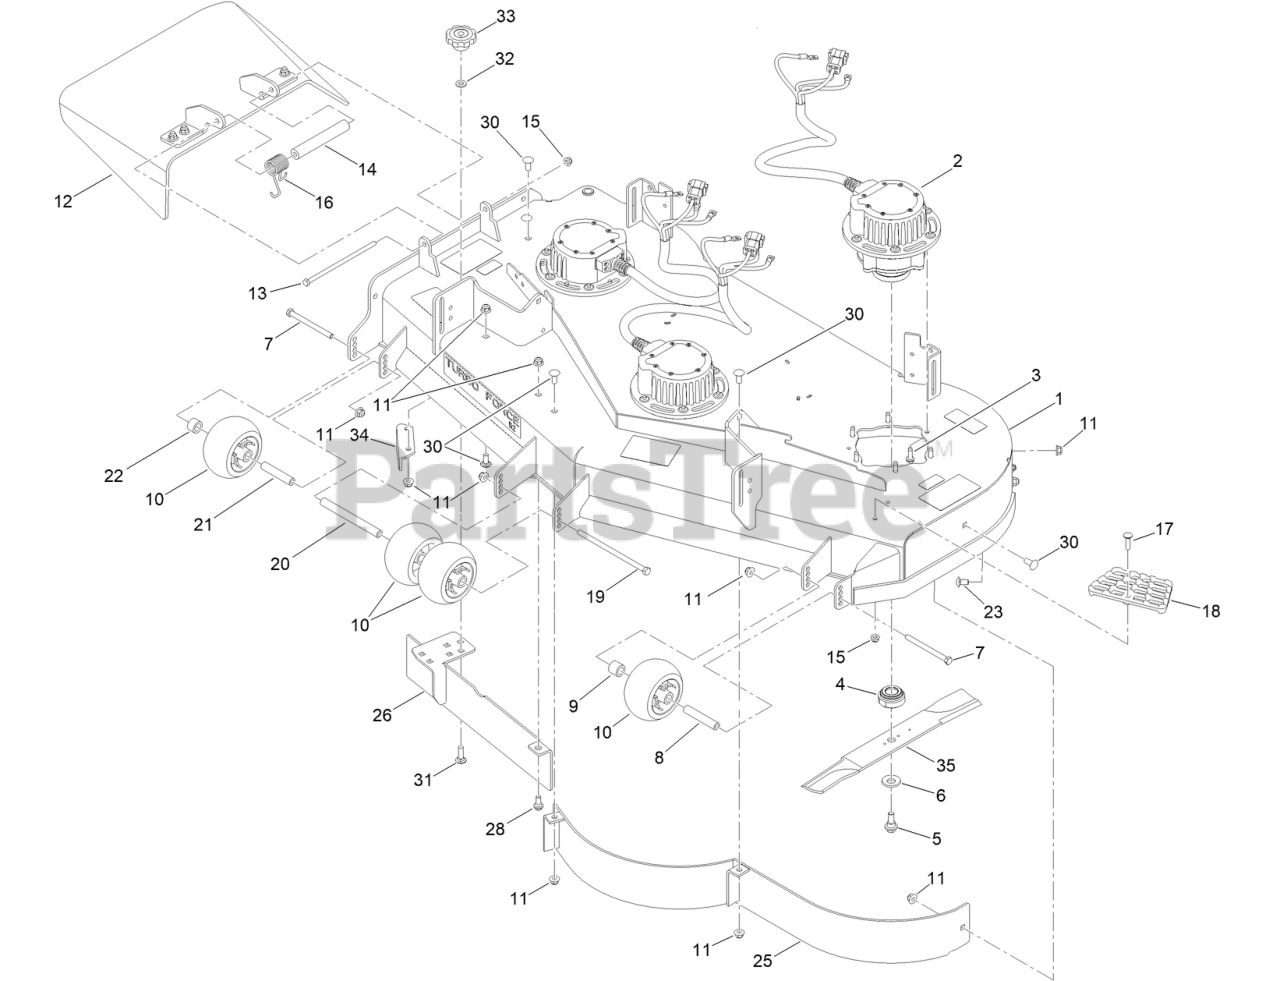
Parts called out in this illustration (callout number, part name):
1	DECK ASM-52IN
2	MOTOR/GEN-48V,
3	SCREW-THD ROLL, HWH
4	RETAINER-BLADE
5	SCREW-SHOULDER,HWH
6	WASHER-BELLEVILLE
7	SCREW-HH
8	TUBE-SPANNER
9	TUBE-SPACER
10	ROLLER-SCALP, ANTI
11	NUT-HF, NI
12	RUBBER DEFLECTOR ASM
13	SCREW-HH
14	SPACER
15	NUT-HF, NI
16	SPRING-TORSION
17	SCREW-CARR
18	STEP-DECK
19	SCREW-HH
20	SPACER-WHEEL
21	TUBE-SHAFTING
22	TUBE-SPACER
23	SCREW-CARR
25	BAFFLE ASM
28	BOLT-SHOULDER
30	SCREW-CARR
31	BOLT-CARR
32	WASHER-HARDENED
34	BAFFLE-DISCHARGE
35	BLADE-18.0IN, MED SAIL
